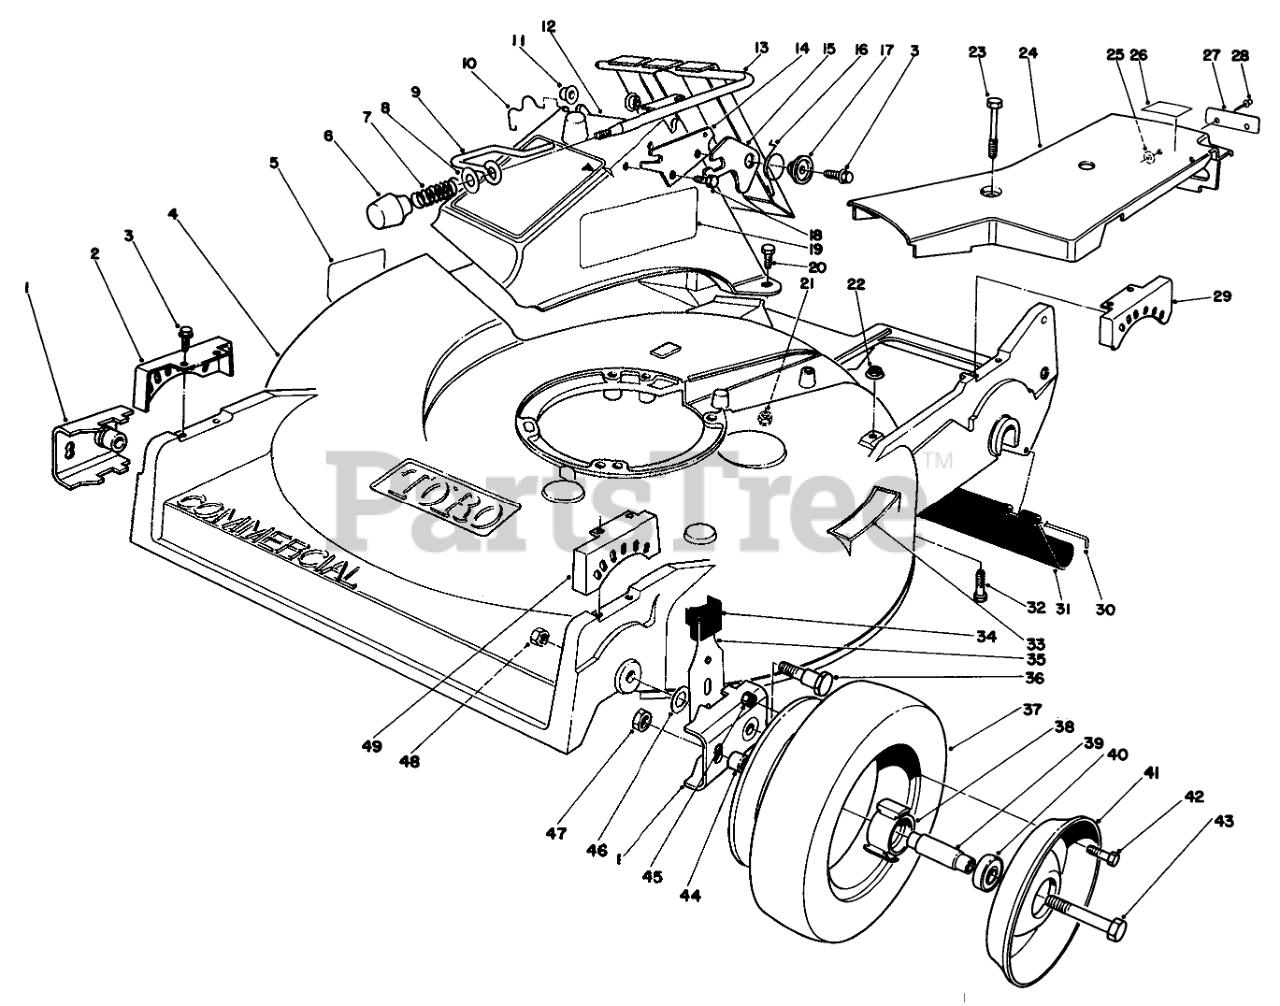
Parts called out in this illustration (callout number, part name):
1	PIVOT ARM
2	QUADRANT-FRONT, RH
3	Screw
4	Housing (Incl. Ref. #5 & 33)
5	DECAL-DANGER
7	COMPRESSION SPRING
8	WASHER-FLAT
9	DOOR LATCH
10	DOOR RETAINER
11	BUSHING-NYLON
12	Chute & Door Assembly (Incl. Ref. #3 8 6-21)
13	DOOR & HANDLE WA
14	DOOR LATCH PLATE
15	SAFETY LATCH
16	TORSION SPRING
17	DOOR SPACER
18	SCREW-HWH
19	DECAL SAF INST
20	SCREW-HH
21	NUT-LOCK, NI
22	NUT-HF
23	SCREW-HHFTF
24	Belt Cover Assembly (Incl. Ref. #25 8 27-28)
25	WASHER-PLAIN
26	LABEL-GREASE
27	NAMEPLATE-GRD SPEED
29	QUADRANT-REAR, LH
30	ROD-SHIELD
31	SHIELD-TRAILING
32	SCREW-HH
33	STEP PAD DECAL
34	KNOB-ARM
35	SPRING ARM ASM-FRONT
36	PIVOT SCREW
38	HUB-BEARING
39	SPACER-BEARING
40	BEARING-WHEEL
41	Wheel-Half
42	SCREW-HHF
43	SCREW-HH
44	SPACER-WHEEL
45	NUT-LOCK, NI
46	WASHER-PIVOT
47	NUT-LOCK, CONE
48	NUT-LOCK, NI
49	QUADRANT-FRONT, LH
